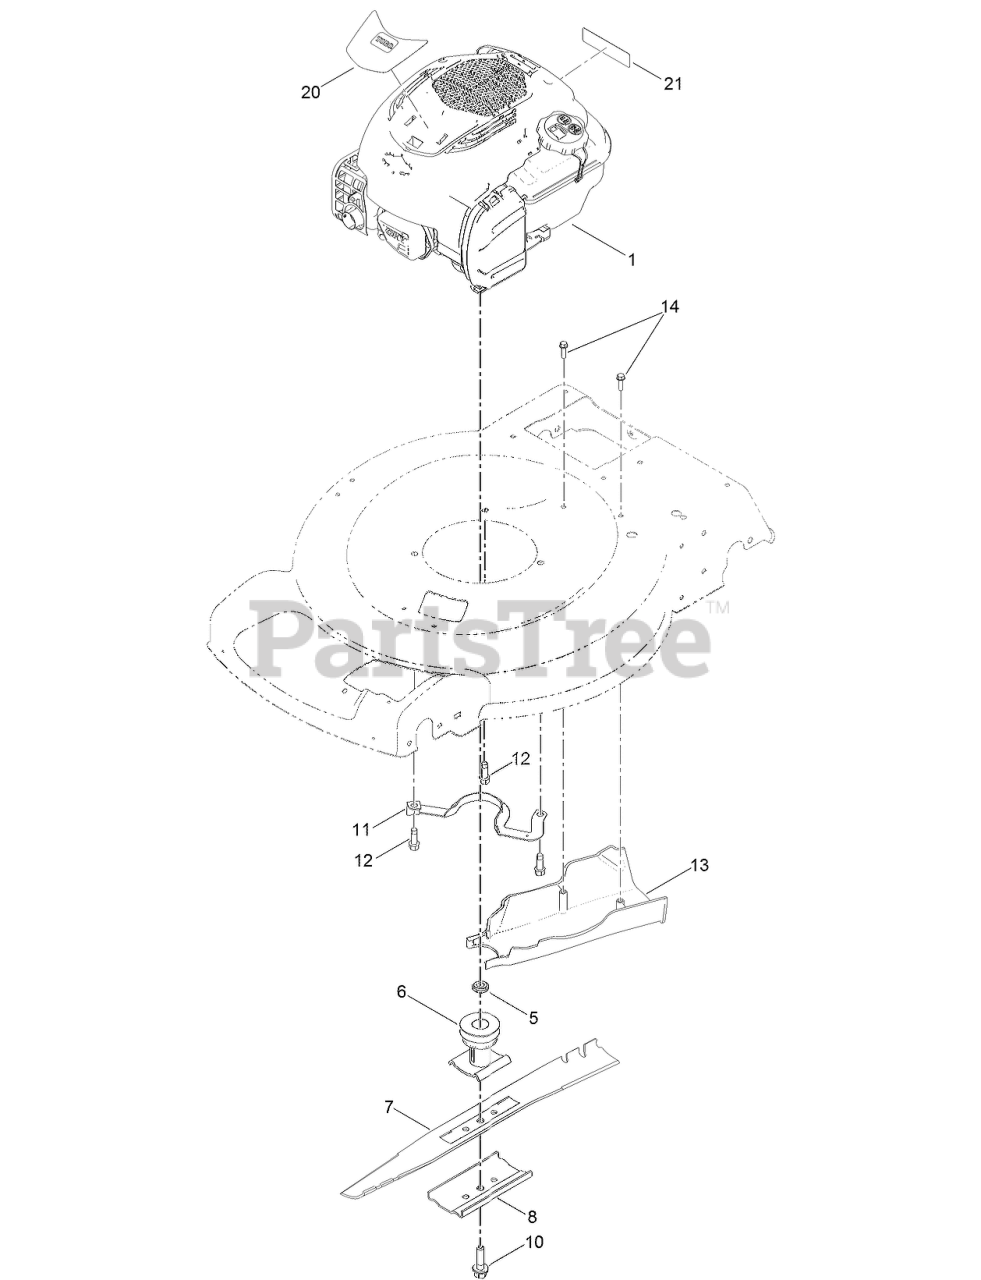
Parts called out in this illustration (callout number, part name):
5	Spacer-Driver
6	DRIVER-BLADE
7	BLADE-22 INCH
8	SUPPORT-BLADE
10	BOLT-BLADE
11	GUIDE-BELT
12	SCREW-TAPTITE
13	COVER-BELT, REAR
14	SCREW-HWH
20	DECAL-SHROUD, BRIGGS
21	DECAL-ARRESTER, SPARK
